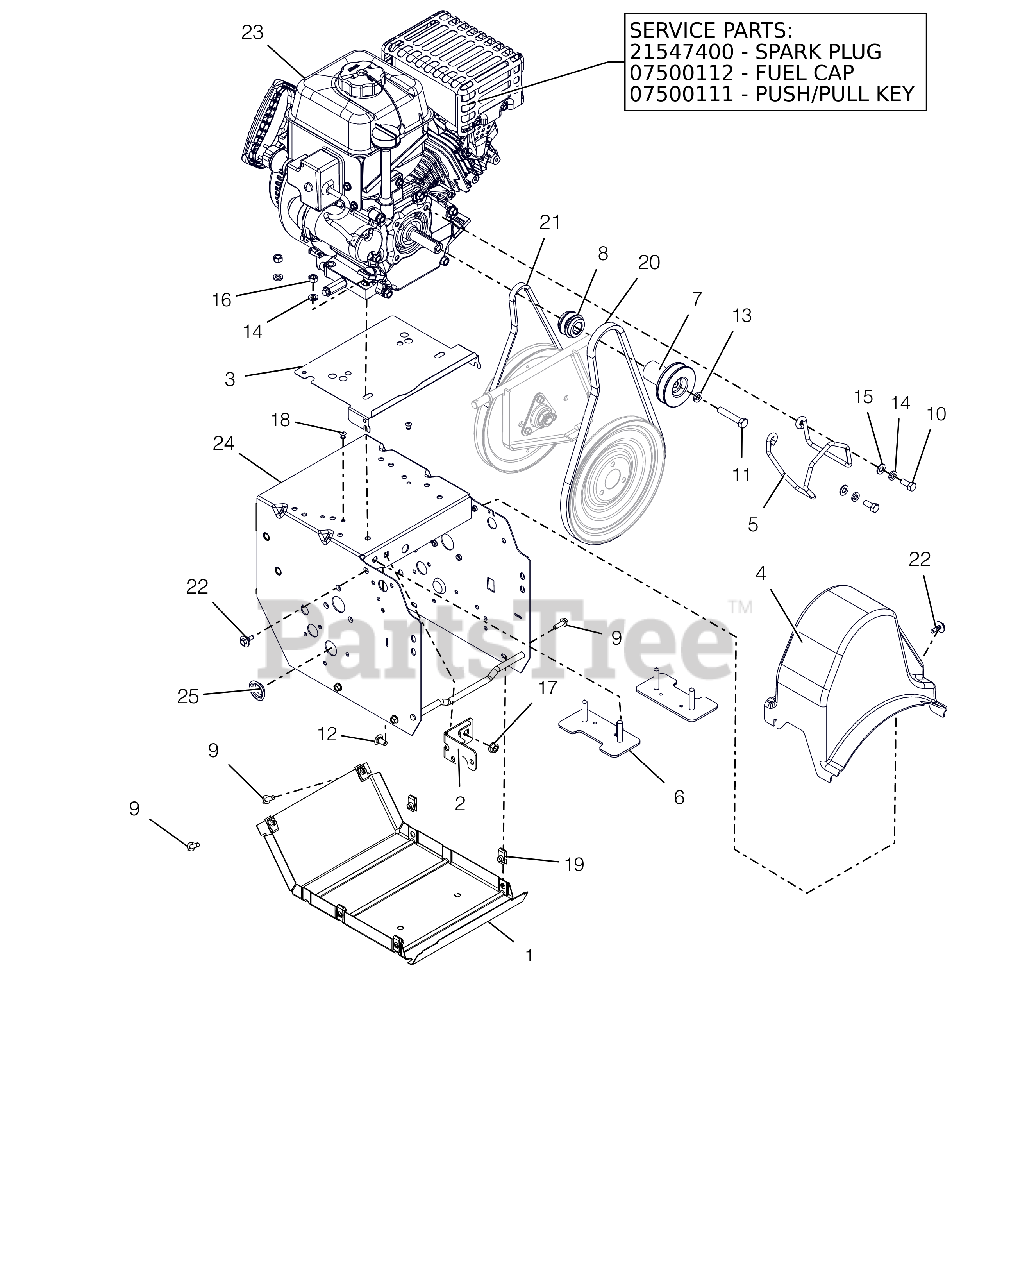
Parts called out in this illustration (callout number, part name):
1	COVER, BOTTOM
2	WELDMENT, FRAME BRACKET
3	BAFFLE, COMPACT
4	COVER, COMPACT BELT
5	FINGER, BELT
6	STRAP, ENGINE BOLT-WELDMENT
7	SHEAVE, AUGER 3/4 - PM
8	TRACTION SHEAVE HALF
9	BLT-HEX .25-20X.75 HWH YZ GR5
10	BLT-HEX .31-24X.75 YWZC GR5
11	BLT-HEX .38-24X2.0 YWZC
12	@BLT-RHDSSQNK .31-18X.62 G5YZ
13	@WSHR-LK .38X.094 REG YWZC
14	WSHR-LK .312X.097 HVY YWZC
15	@WSHR-FL-STL.344X.688X.065YWZC
16	@NUT-HEX .31-18 YWZC
17	@NUT-LK-TOP-FLG .31-18 YWZC
18	RVT-POP .187 YZ
19	NUT-RTNR .25-20X.56
20	V-BELT, HA-RAW EDGE
21	V-BELT, 3L-WRAPPED
22	SCR-TAP .25-20X.5 CAPTIVE
23	ENGINE, SNO-TEK 208 240V
23	PLUG, SPARK
23	CAP, FUEL TANK BLACK
23	KEY, PUSH/PULL LCT (2/PACKAGE)
24	FRAME, MAIN
25	PLUG, HOLE - 1.00" FLEXTEMP
